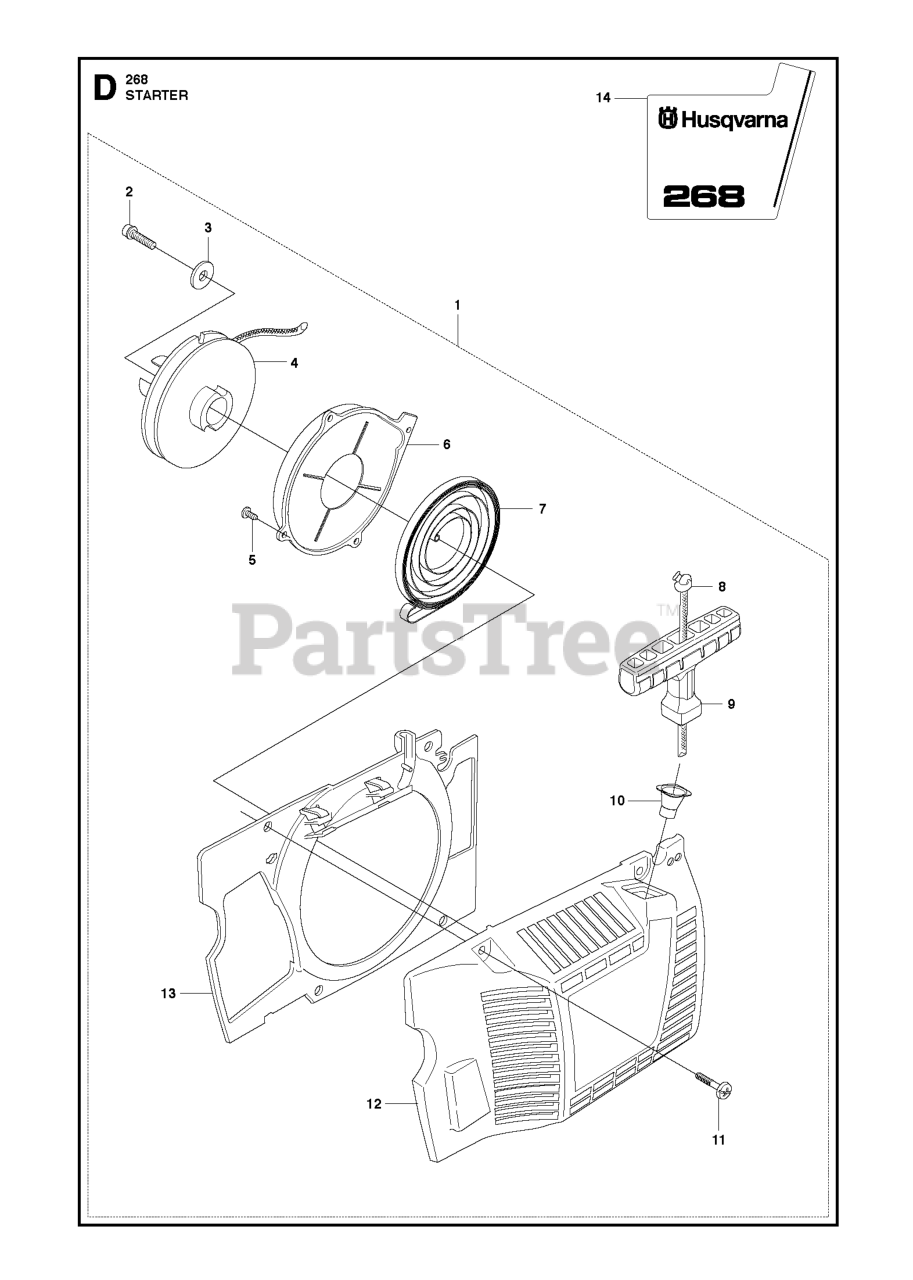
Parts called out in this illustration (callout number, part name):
1	STARTER DEVICE CPL
2	SCREW IHSCFT PW5.5X16 8.8 ZN/
4	STARTER PULLEY
7	RECOIL SPRING
8	STARTER ROPE
9	STARTER HANDLE
11	SCREW
12	STARTER HOUSING
13	AIR CONDUCTOR
